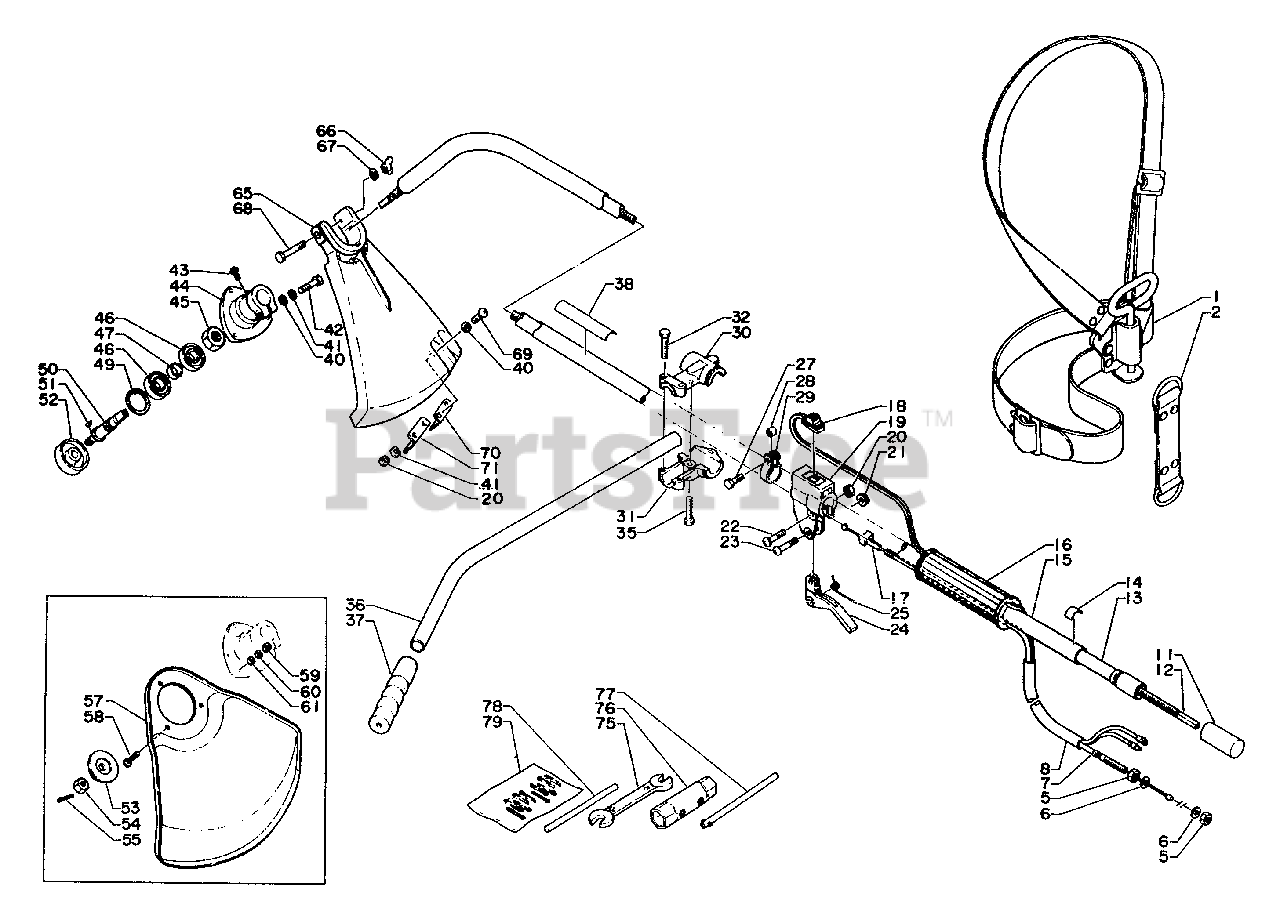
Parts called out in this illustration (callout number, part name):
1	SHOULDER STRAP ASSY
2	STRAP
6	WASHER - 6
7	CABLE, THROTTLE
8	TUBE
11	CAP
12	DRIVESHAFT - FLEXIBLE
13	LINER
14	LABEL - ALIGNMENT
15	PIPE, MAIN
16	GRIP, HANDLE
17	GUIDE, CABLE
18	IGNITION SWITCH ASSY
19	BRACKET, THROTTLE
21	LOCKNUT - 5
22	SCREW - 5X28
23	SCREW - 5X30
24	TRIGGER, THROTTLE
25	SPRING, TRIGGER
27	BOLT - 5X18
30	BRACKET
31	BRACKET
32	BOLT - 5X25
35	BOLT - 5X28
36	HANDLE
37	GRIP, HANDLE
38	LABEL - CAUTION
40	WASHER - 5
41	LOCKWASHER - 5
42	BOLT - 5X25
43	SCREW - 4X10
44	CASE, BEARING
45	NUT - 12 -- LEFT HAND
46	BEARING, BALL - 6001 DDU
49	RING, RETAINING - 28
50	GEAR - SHAFT
52	ADAPTOR, BLADE - UPPER
53	ADAPTOR, BLADE - LOWER
54	NUT - 3/8-24
55	PIN, SPLIT
57	SHIELD ASSY - METAL
58	SCREW - 4X18
60	LOCKWASHER - 4
61	WASHER - 4
65	SHIELD ASSY - PLASTIC
66	WINGNUT - 6
67	WASHER - 6
68	BOLT - 6X50
69	SCREW - 5X14
70	KNIFE, TRIMMER LINE
75	SPANNER - 8X10mm
76	SOCKET WRENCH - 17X19mm
77	ROD, HANDLE
78	LOCKING TOOL
79	PIN, SPLIT - 2X22
